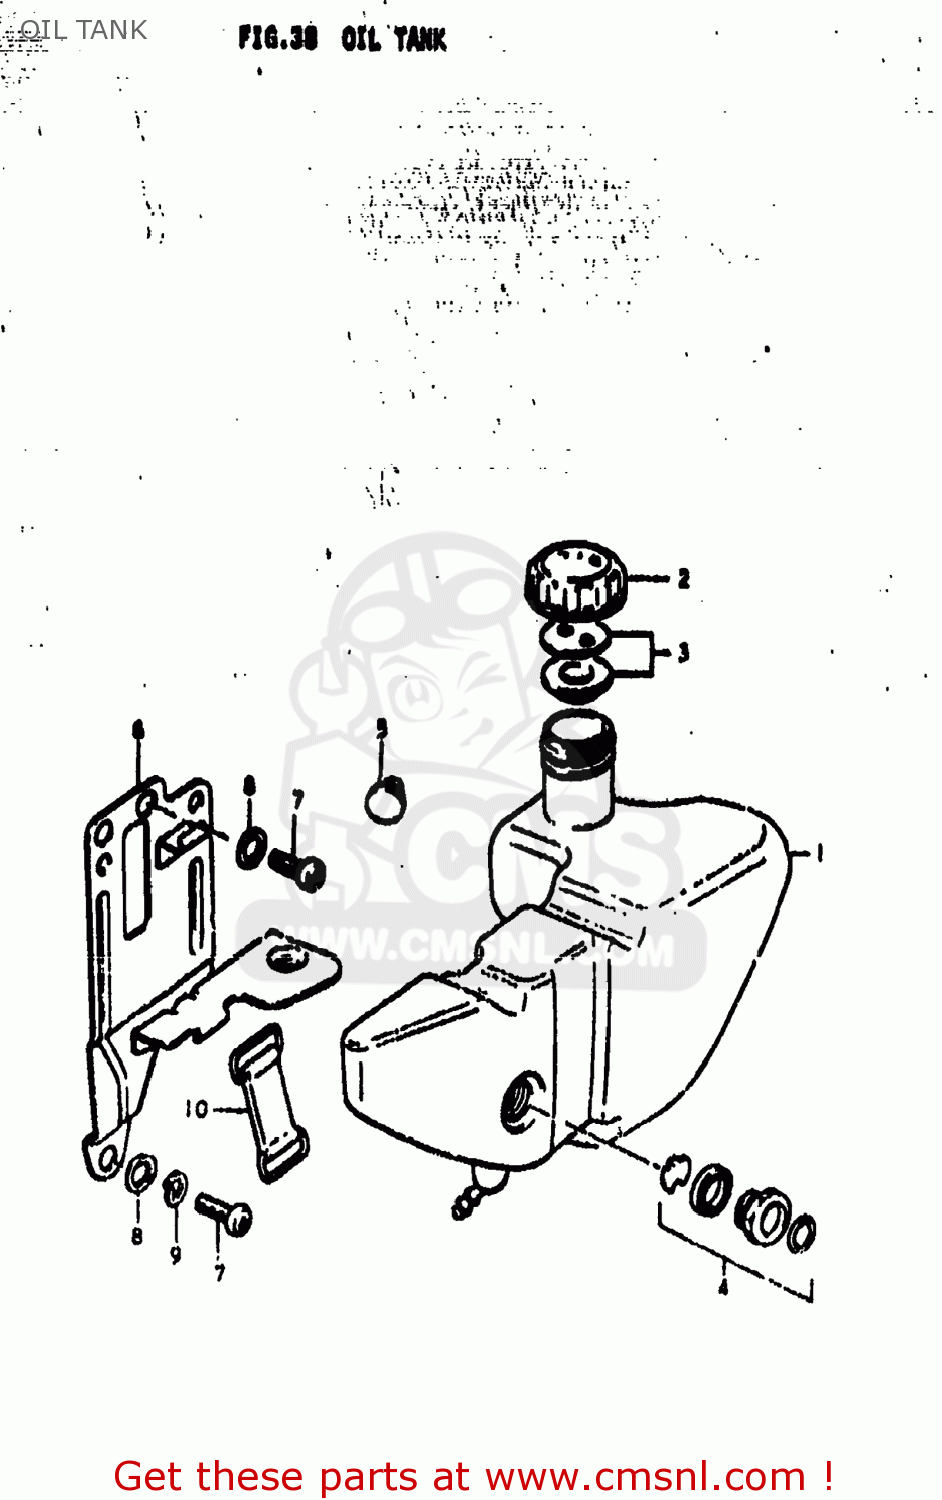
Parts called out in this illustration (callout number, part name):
1	TANK,OIL
2	CAP,OIL TANK
3	LENS,OIL LEVEL INSPECTION
4	LENS,OIL LEVEL INSPECTION
5	CUSHION
7	SCREW
8	WASHER
9	LOCK WASHER
10	BAND
